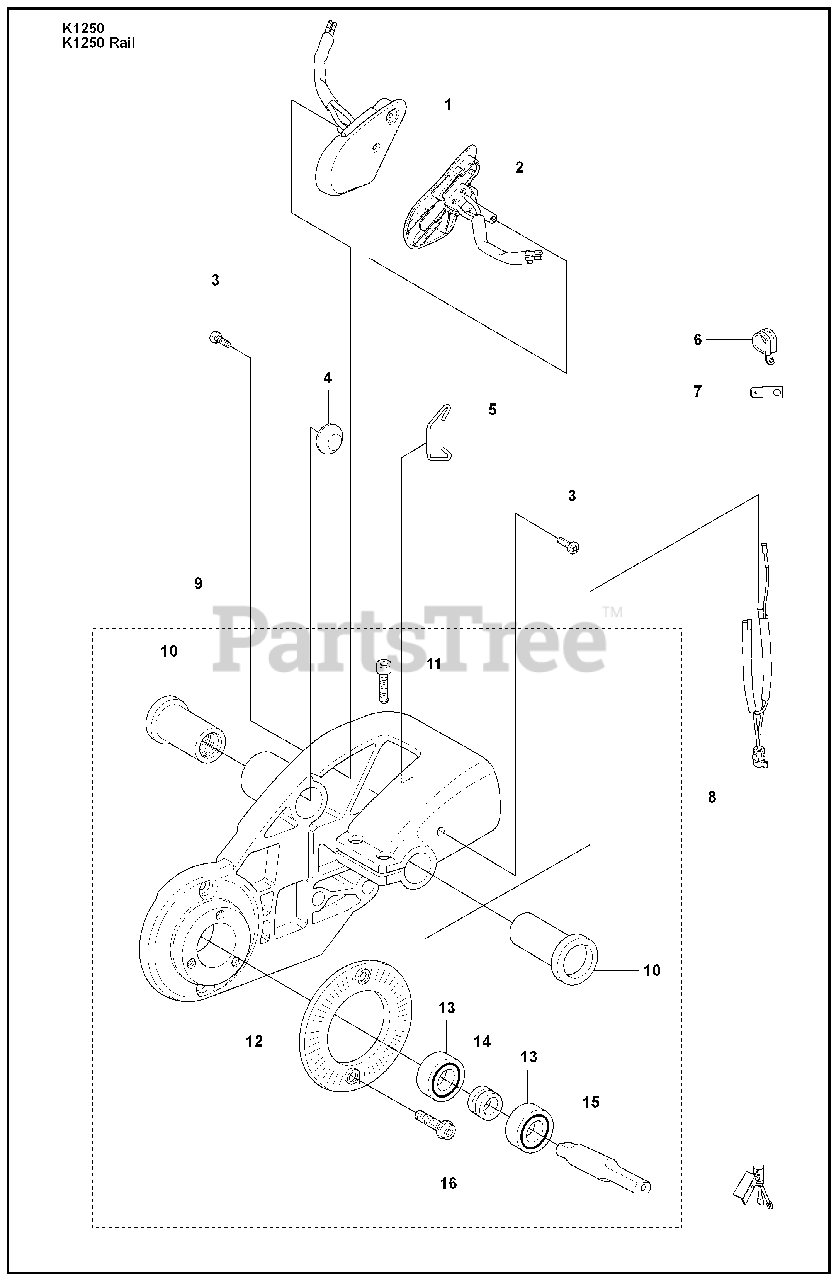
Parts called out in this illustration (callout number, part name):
1	STOP SWITCH
2	STOP SWITCH
4	SPACING BLOCK
7	CONNECTION PLATE
9	BEARING HOUSING
12	SCREEN PATTERN FLANG
13	BALL BEARING
14	SPACING SLEEVE
